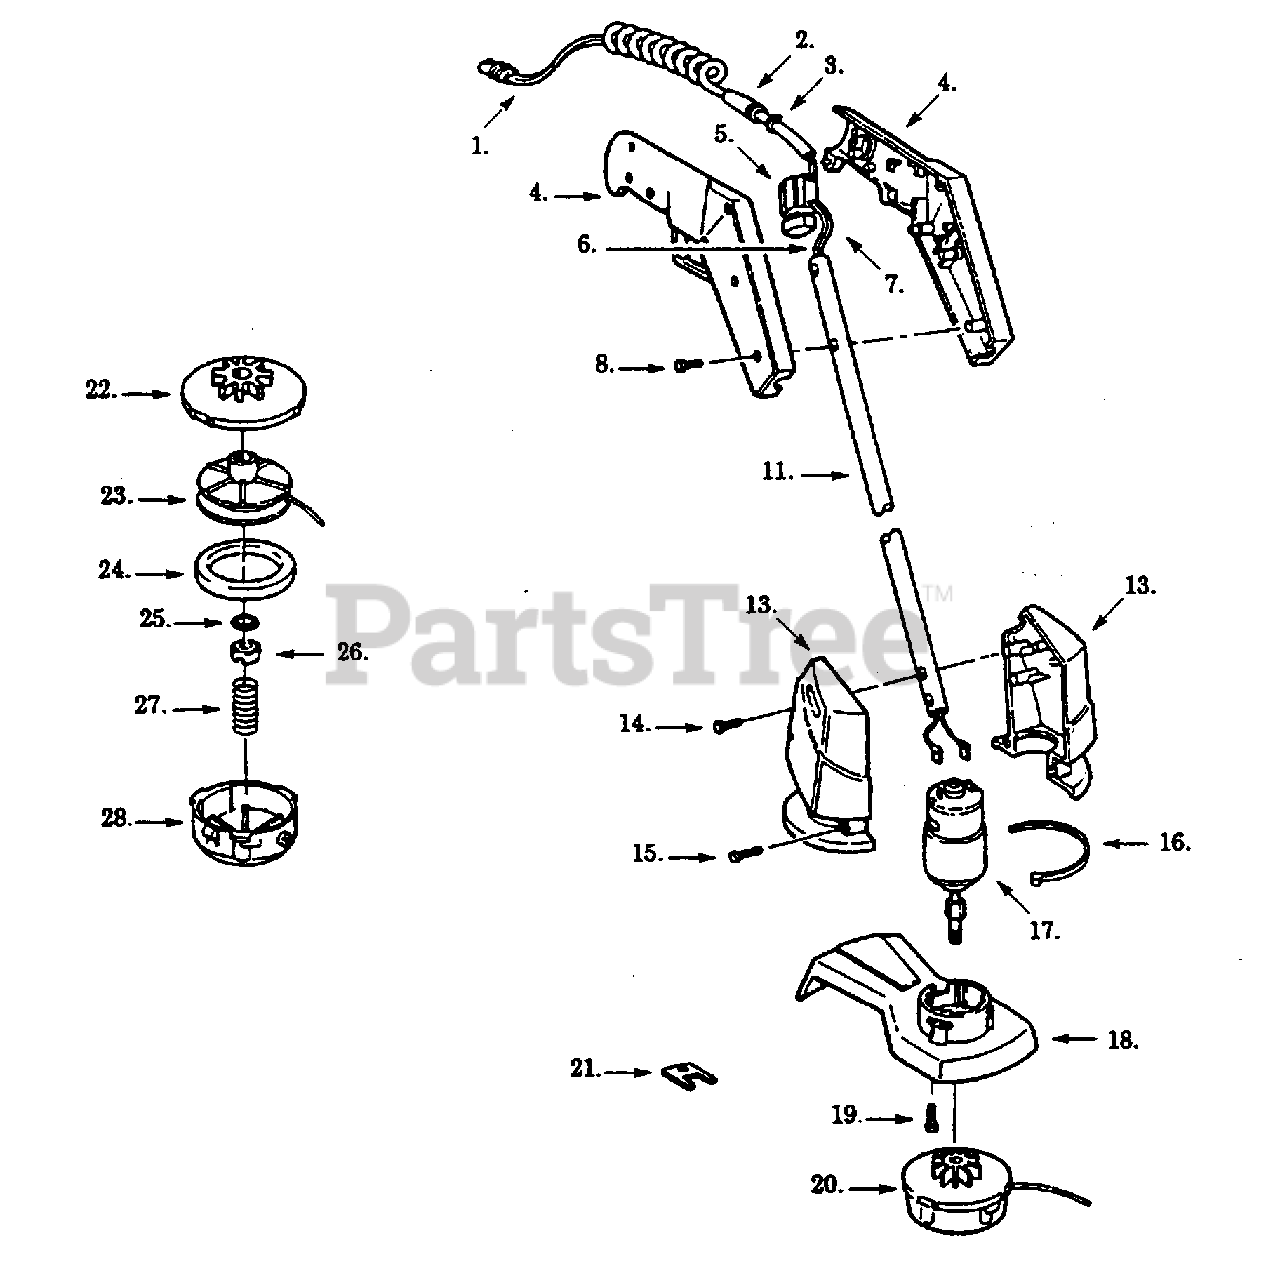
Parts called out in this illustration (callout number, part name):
1	Coiled Cord
2	Rubber Strain Relief
3	Strain Relief
4	Handle Set
5	Trigger Switch
6	Lead Wire (Black)
7	Lead Wire (Red)
13	Housing Set
16	Tie Wrap
17	Motor/Adapter Ass'y.
18	Guard/Blade Ass'y.
20	Head Ass'y.
21	Spanner Wrench
22	Rear Plate
23	Spool & Line
24	Foam Pad
26	Adapter Nut
28	Hub Ass'y.
